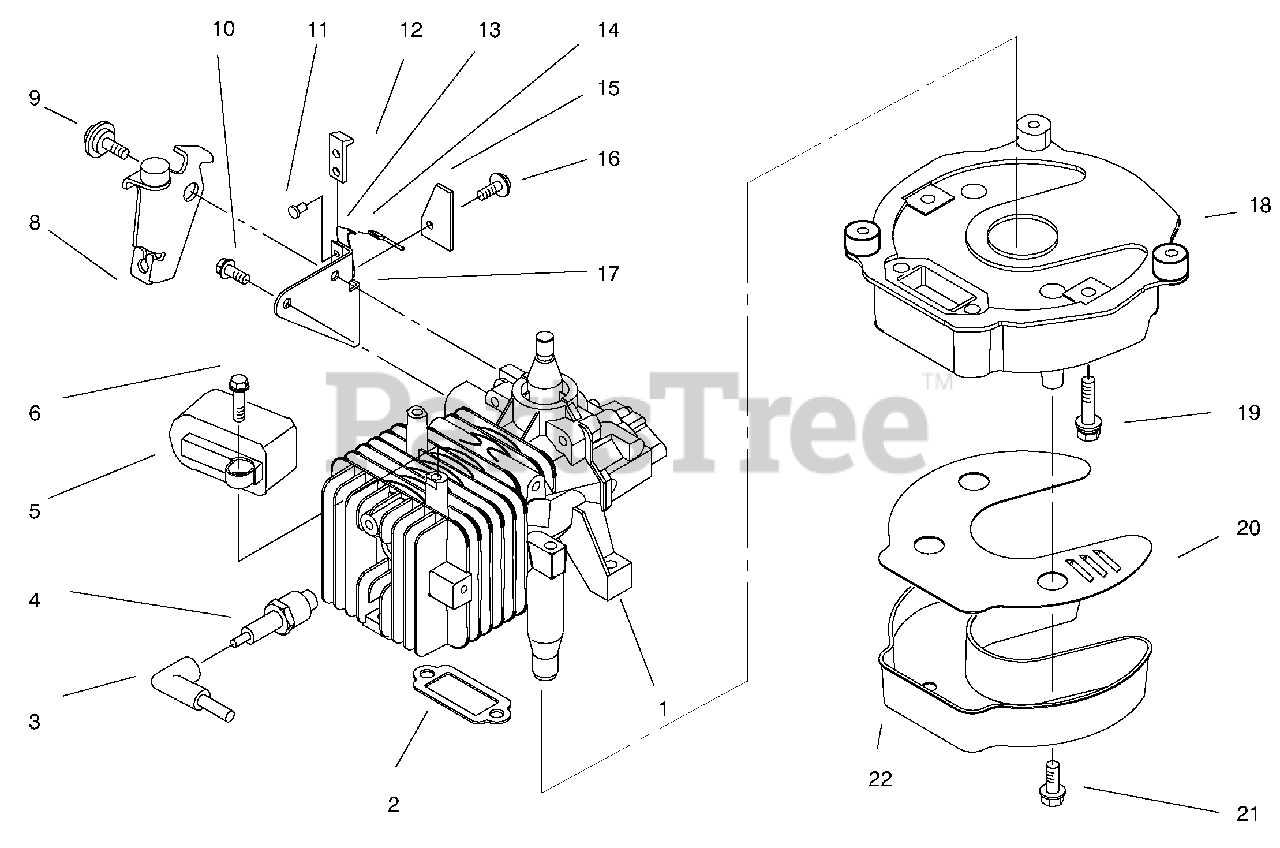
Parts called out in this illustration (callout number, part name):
1	Short Block (Incl. Ref. #2, Ref. #9 pg. 8)
2	Gasket-Exhaust
3	CD Ignition
4	Plug-Spark
5	CD Ignition (Incl. Ref. #3)
6	Screw-Hex. Washer Hd.
8	Brake Plate Assembly
9	Screw-Shoulder
10	Screw
11	Rivet-Plastic
12	Strap-Insulation
13	Strap-Ground
14	Wire-Brake Switch Lead
15	Stop-Ground Strap
16	Screw-Thread Forming
18	Plate-Muffler
22	Cover-Muffler
